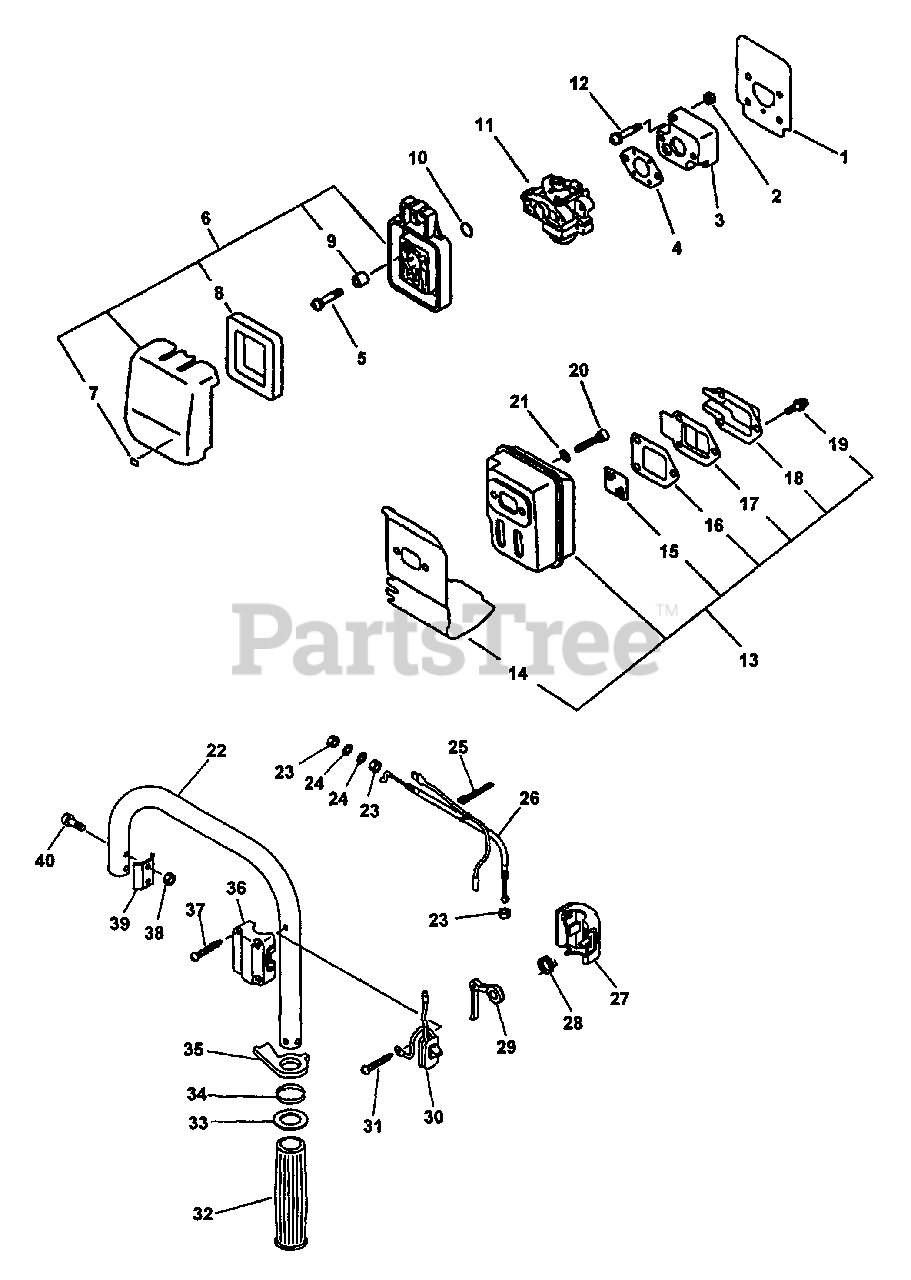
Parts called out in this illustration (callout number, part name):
1	SHIELD, INTAKE
3	INSULATOR, INTAKE
4	GASKET, INTAKE
5	SCREW - 5X20
6	AIR CLEANER ASSY
8	FILTER, AIR
9	SLEEVE
10	O-RING - 15
11	CARBURETOR WYL-56
12	SCREW - 5X64
13	MUFFLER ASSY
14	GASKET, EXHAUST
15	SCREEN, SPARK ARRESTOR
16	GASKET, EXHAUST
17	GASKET, EXHAUST - INNER
18	GUIDE, EXHAUST
19	SCREW - 4X10
20	SCREW - 5X55
21	WASHER - 5
22	HANDLE - REAR
24	WASHER - 6
25	TIE, CABLE
26	CONTROL CABLE ASSY
27	BRACKET, THROTTLE CONTROL - RIGHT
28	SPRING, TRIGGER
29	TRIGGER, THROTTLE
30	IGNITION SWITCH ASSY
31	SCREW - 4X30
32	GRIP, HANDLE - RIGHT
33	SPACER
34	SPRING, LOCKOUT LEVER
35	LEVER, TRIGGER LOCKOUT
36	BRACKET, THROTTLE CONTROL - LEFT
37	SCREW - 4X25
38	LOCKNUT - 5
39	PLATE, HANDLE
40	SCREW - 5X35
